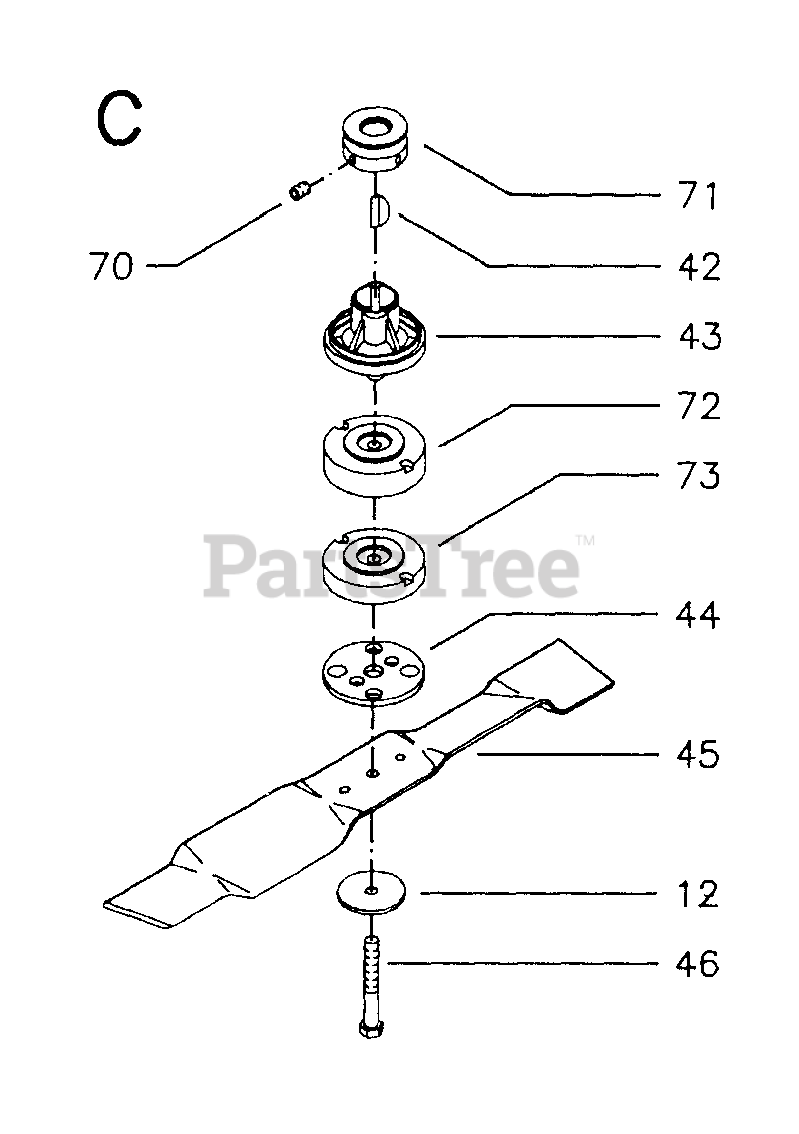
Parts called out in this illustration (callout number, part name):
42	WOODRUFF KEY
43	BLADE ADAPTER
44	STEEL PLATE ADAPTER
72	SPACER
73	SPACER
